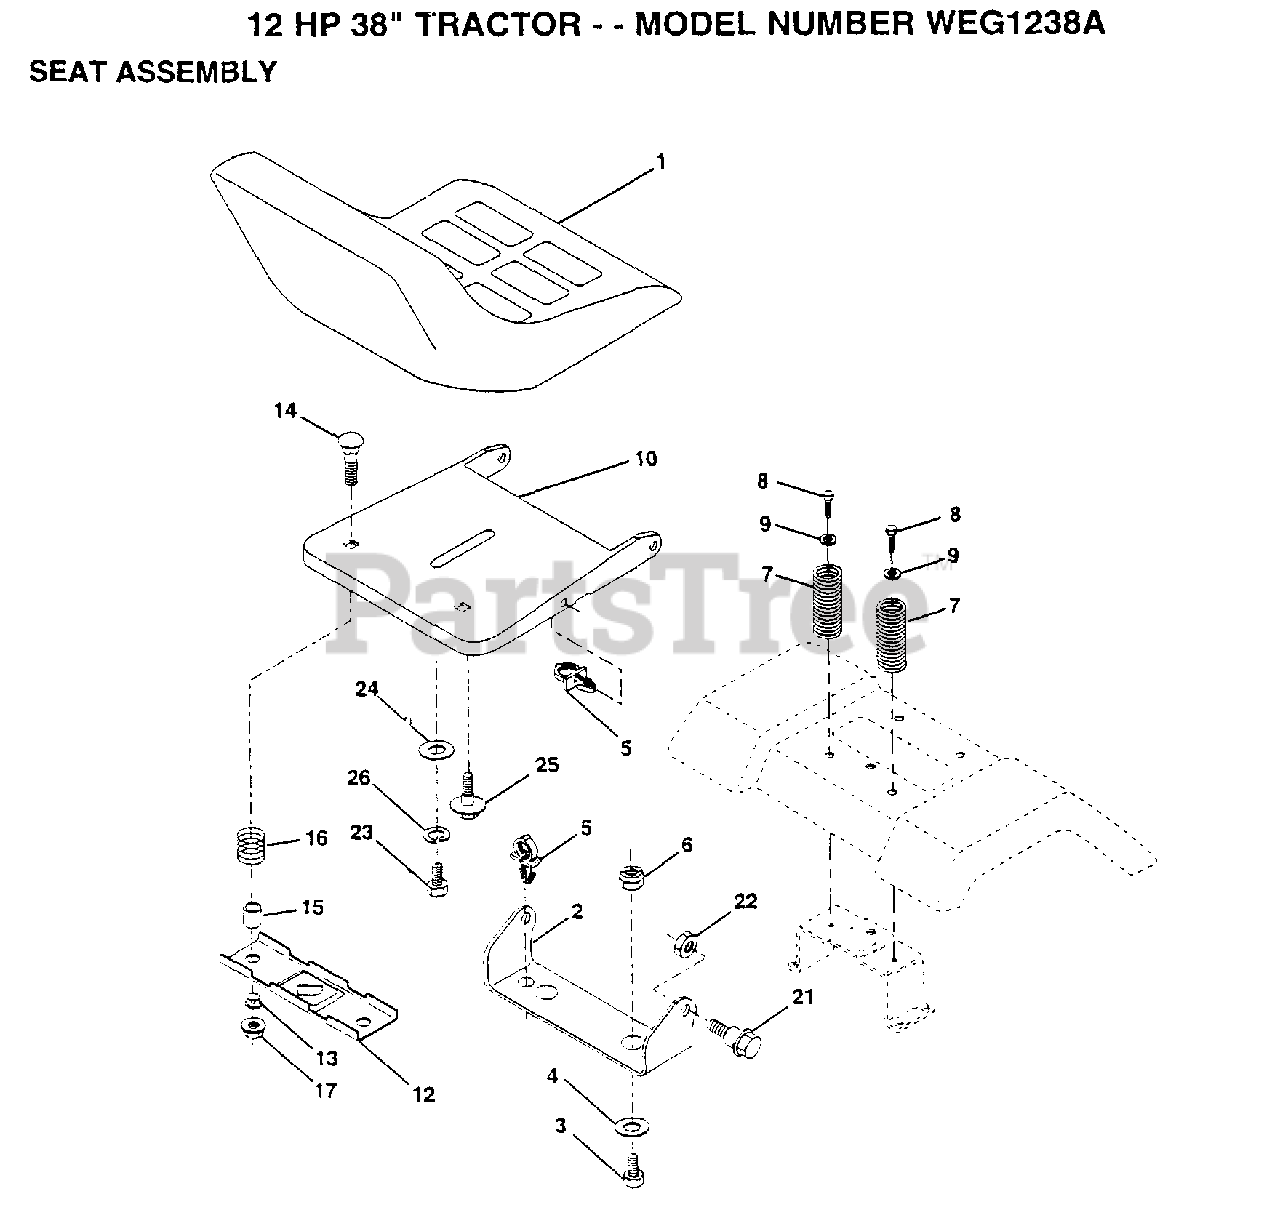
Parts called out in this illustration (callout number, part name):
2	BRACKET PVT SEAT
3	BOLT
4	WASHER PM
5	CLIP PUSH - IN
6	NUT
7	SPRING COMPRESSIO
8	SCREW GTV
9	WASHER
12	BRKT SWITCH
13	BUSHING
15	SPLIT SPACER
16	SPRING
21	BOLT.SHLD.5/16-18
22	NUT
23	BOLT
24	WASHER
25	"BOLT,SHOULDER"
26	LOCKWASHER
